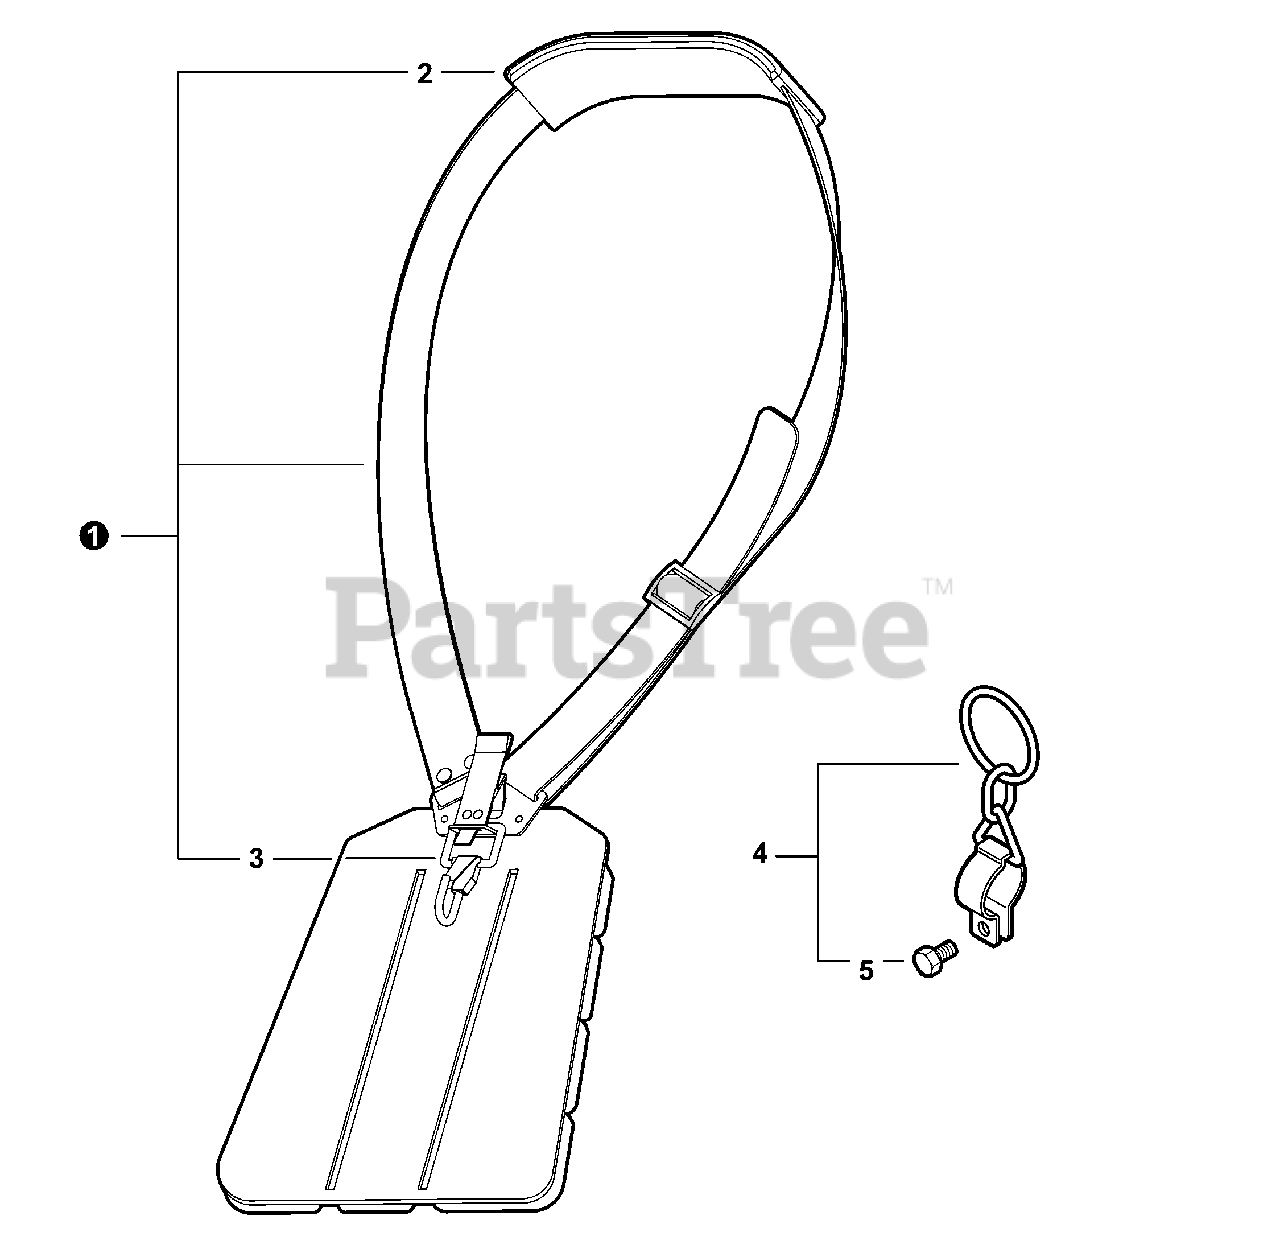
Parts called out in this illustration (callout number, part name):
1	HARNESS ASSY, BRUSHCUTTER
2	PAD, SHOULDER
3	HOOK, SNAP
4	HANGER SET, HARNESS
5	BOLT 5×12
